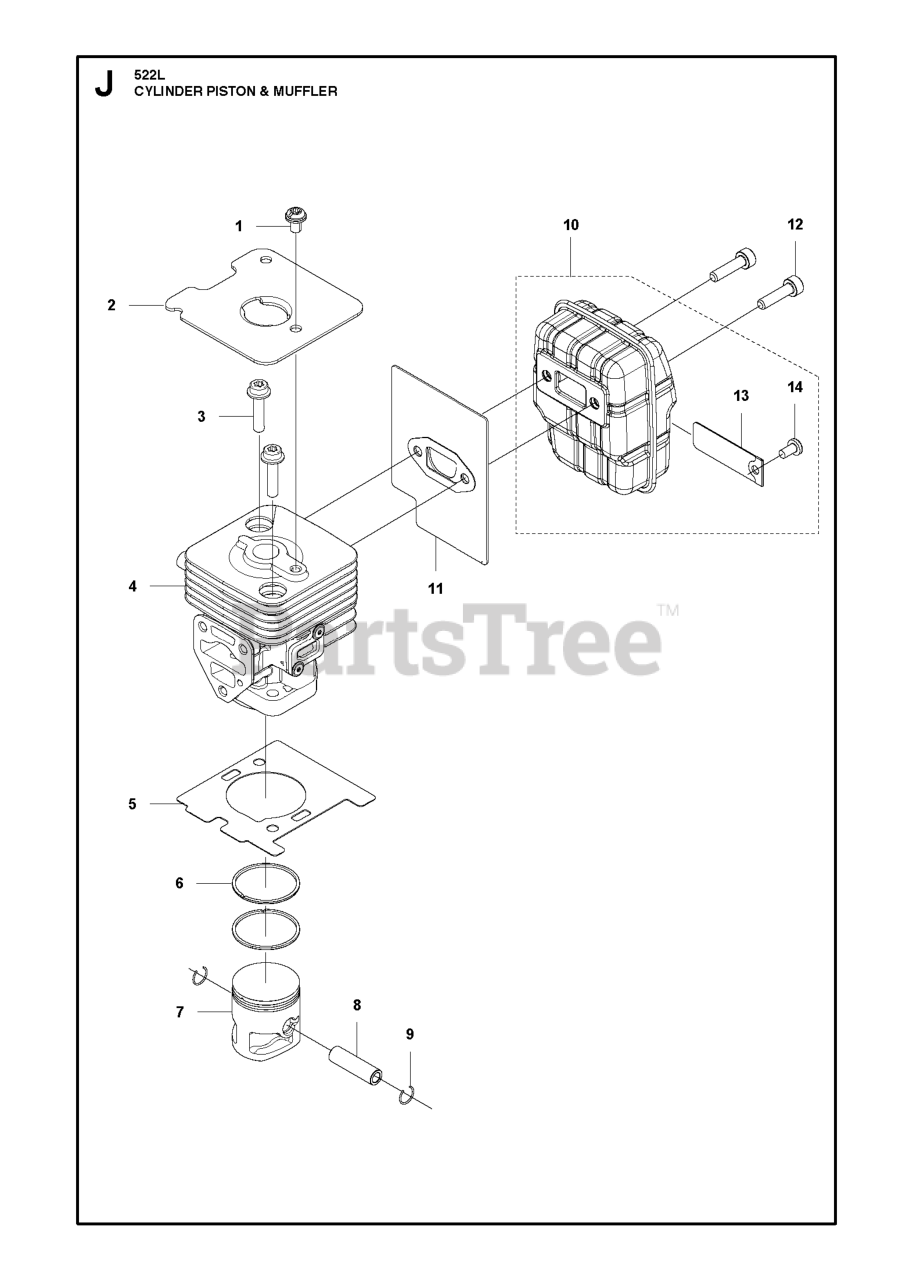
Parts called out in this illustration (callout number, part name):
4	CYLINDER COMP
5	GASKET BASE
6	RING PISTON
8	PIN.PISTON 8488B82600
10	MUFFLER ASSY
11	GASKET MUFFLER
12	BOLT
13	SPARK ARRESTER
14	SCREW CRPANT TYPE F ST4.2X9.5
